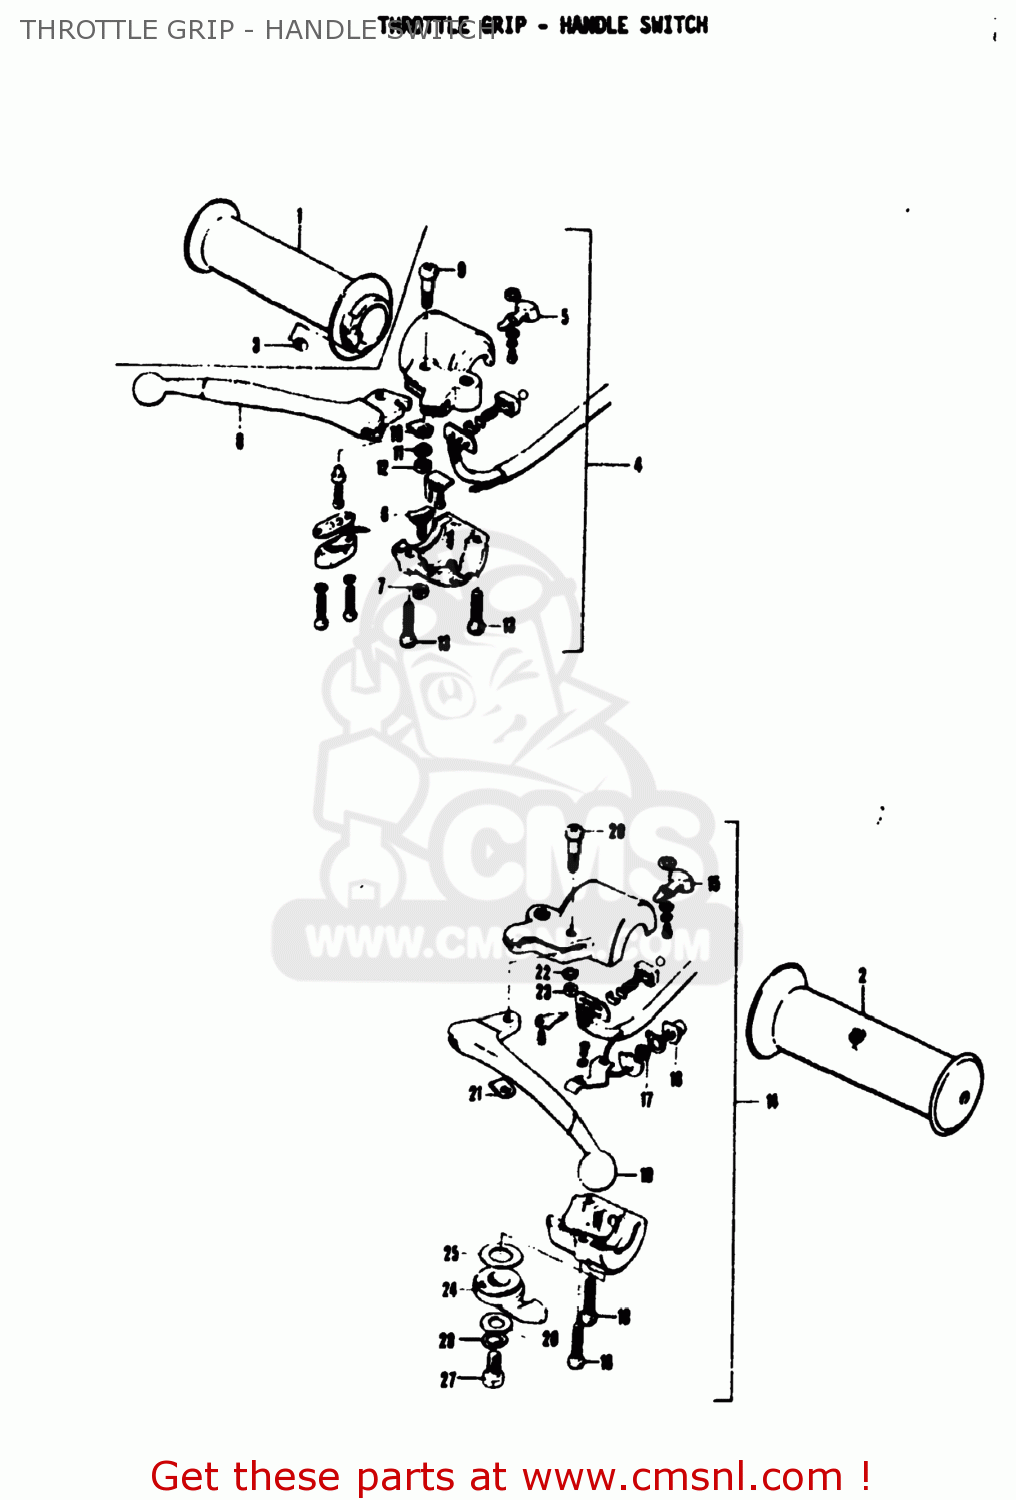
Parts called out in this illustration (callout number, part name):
1	GRIP,THROTTLE
2	GRIP
3	PIECE,THROTTLE END
4	LEVER/SWITCH ASSEMBLY,BRAKE
5	KNOB,DIMMER SWITCH
6	ADJUSTER,GRIP
7	NUT
8	LEVER,BRAKE
9	BOLT,LEVER
10	SPACER,LEVER
11	LOCK WASHER
12	NUT
13	SCREW
14	LEVER ASSEMBLY
15	KNOB,DIMMER SWITCH
16	BUTTON
17	SPRING
18	SCREW
19	LEVER,CLUTCH
20	BOLT,LEVER
21	SPACER,LEVER
22	LOCK WASHER
23	NUT
24	LEVER,STARTER
25	WASHER,ADJUSTER
26	WASHER,STARTER LEVER
27	BOLT
28	LOCK WASHER
